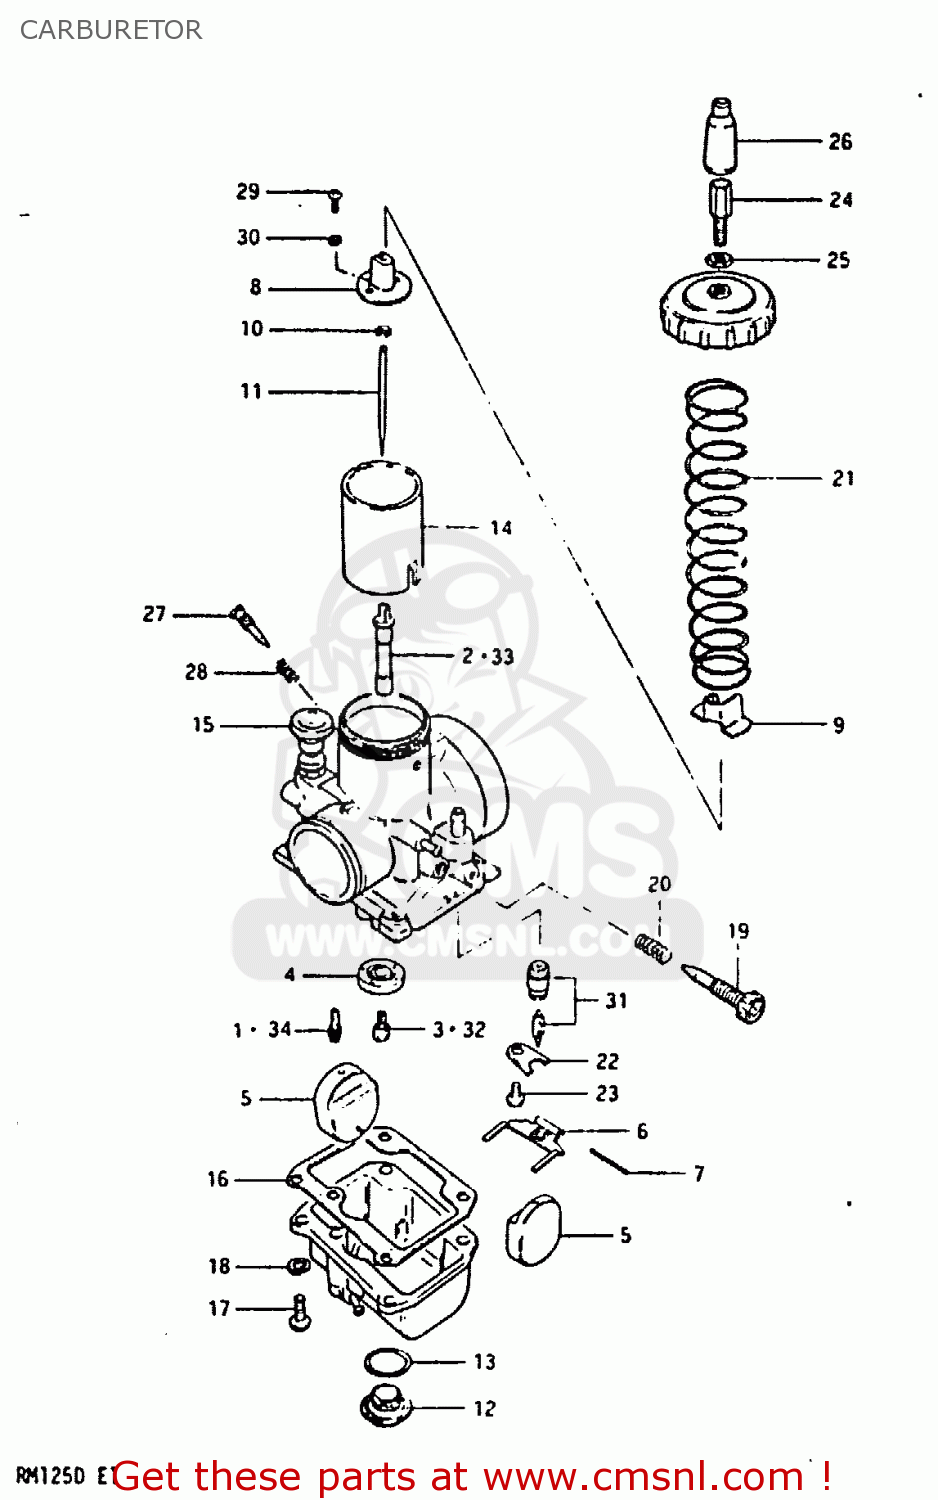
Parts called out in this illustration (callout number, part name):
1	JET
2	JET,NEEDLE
3	JET
4	RING,MAIN JET FIXING
5	FLOAT
6	ARM,FLOAT
7	PIN,FLOAT
8	CONNECTOR
9	COVER,HOLDER
10	CLIP
11	NEEDLE,JET
12	PLUG
13	O RING(D:1.5,ID:19.5)
14	VALVE,THROTTLE
15	VALVE ASSEMBLY,STARTER
16	GASKET,FLOAT CAHMBER (NAS)
17	SCREW
18	LOCK WASHER
19	SCREW,THROTTLE STOP
20	SPRING
21	SPRING,THROTTLE VALVE RETURN
22	PLATE
23	SCREW 4X6
24	ADJUSTER,CABLE
25	NUT
26	CAP,CABLE ADJUSTER
27	SCREW,PILOT AIR
28	SPRING
29	SCREW
30	LOCK WASHER
31	VALVE ASSY,NEEDLE
32	JET
33	JET,NEEDLE
34	JET
